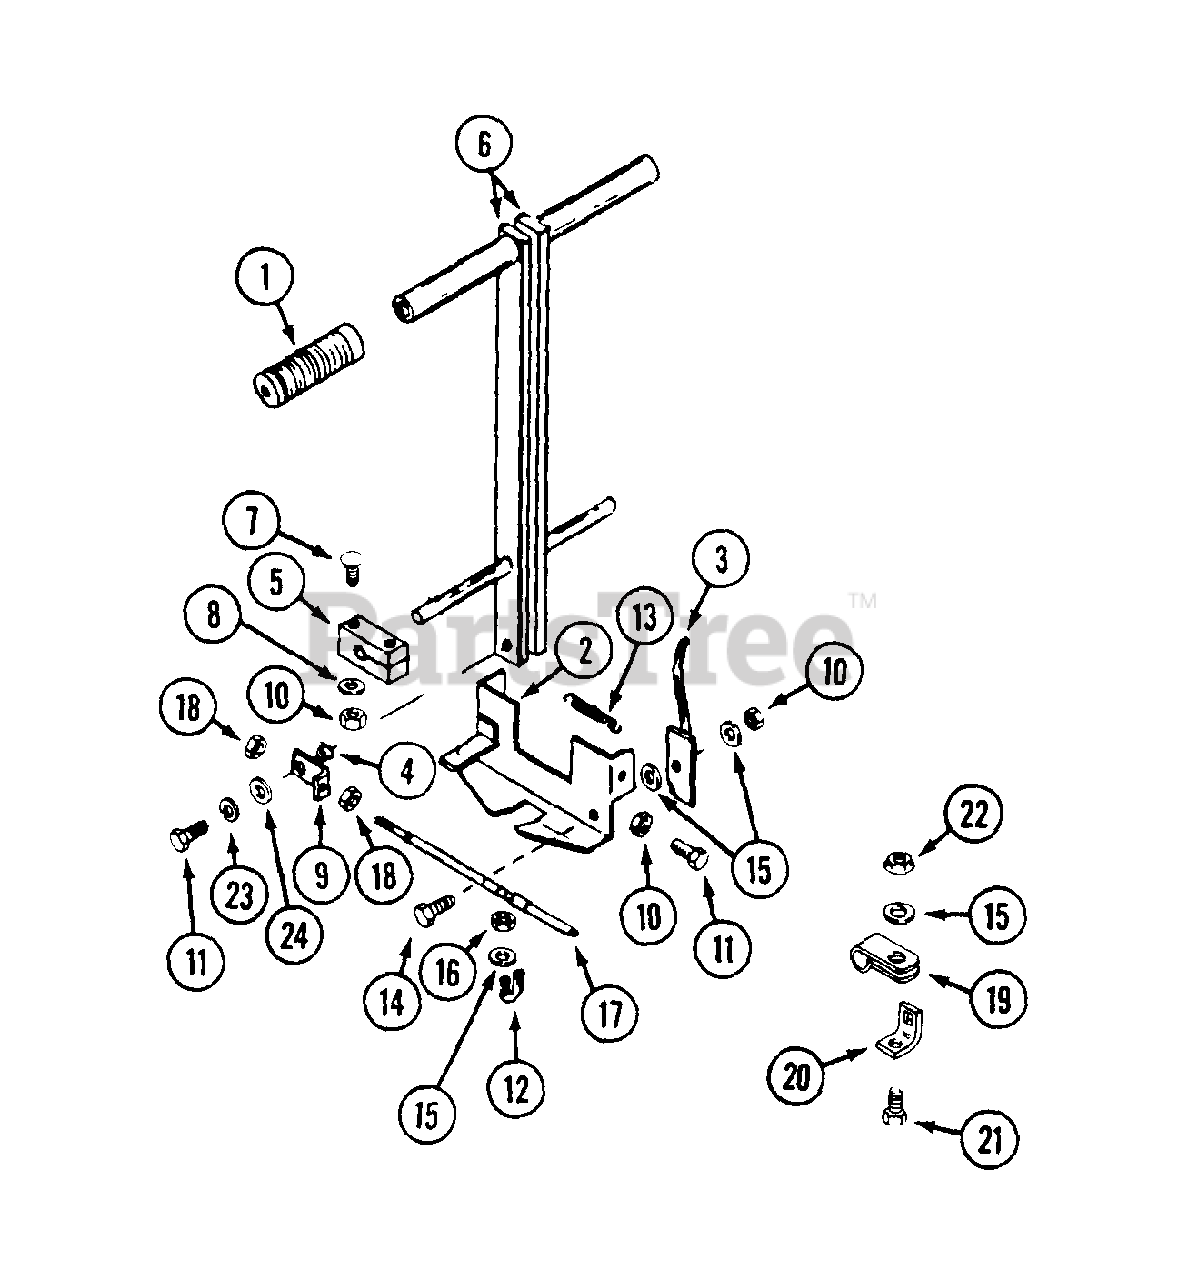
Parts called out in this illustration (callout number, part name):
1	GRIP - handle
2	BRACKET - lever lock
3	LATCH - lever lock
4	BUSHING - steering cable
5	BLOCK - bearing
6	LEVER - steering
7	BOLT - 1/4" - 20 x 1-1/2" carriage
8	WASHER - 1/4"
9	BRACKET - steering cable end
10	NUT - 1/4" - 20 lock
11	BOLT - 1/4" - 20 x 3/4"
12	CLAMP - cable
13	SPRING - lever lock
14	BOLT - 1/4" - 20 x 2"
15	WASHER - 1/4"
16	NUT - 5/16" - 18 lock
17	CABLE - steering
18	NUT - 1/4" - 28"
19	CLAMP
20	STOP - brake lever
21	BOLT - 1/4" - 20 x 1/2"
22	NUT - 1/4" - 20 flange lock
23	LOCKWASHER - 1/4"
24	WASHER - 1/4"
